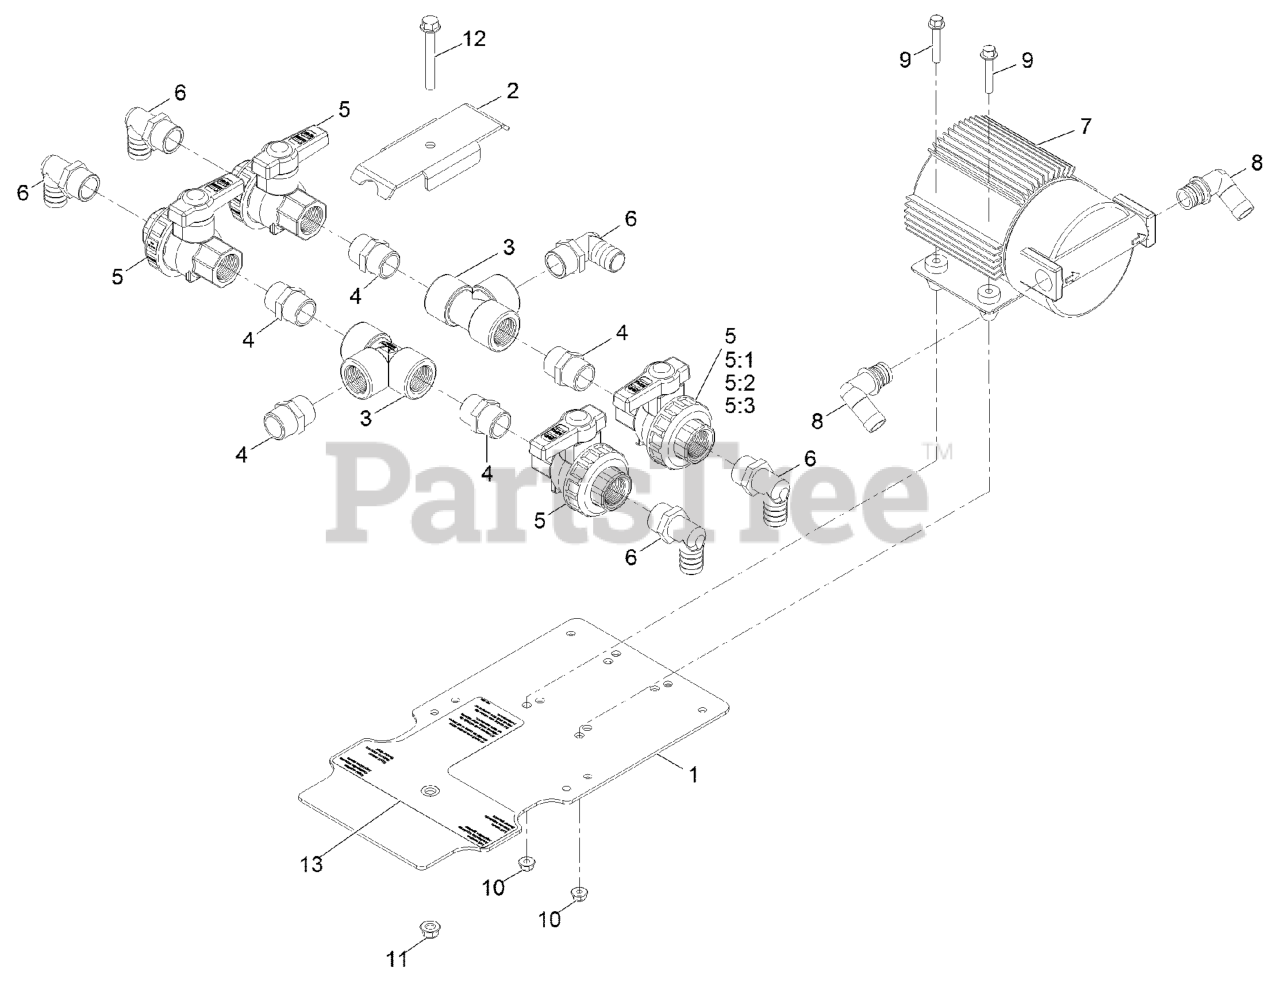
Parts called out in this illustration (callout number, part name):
1	MOUNT-PLATE, LIQUID VALVE
2	PLATE-CLAMP, LIQUID VALVE
3	FITTING-TEE
4	FITTING-NIPPLE
5	VALVE-UNION, 3/4
5:1	O-Ring
5:2	Ring-Valve, Union 3/4
5:3	Adapter-Uv, 3/4
6	FITTING-ELBOW, 90
7	PUMP-7.0 GPM
8	FITTING-ELBOW, 3/4QD X 3/
9	Screw-HHF
10	Nut-Hex Flange
11	Nut-Hex Flange
12	Screw-HHF
13	DECAL-VALVE, TANK
